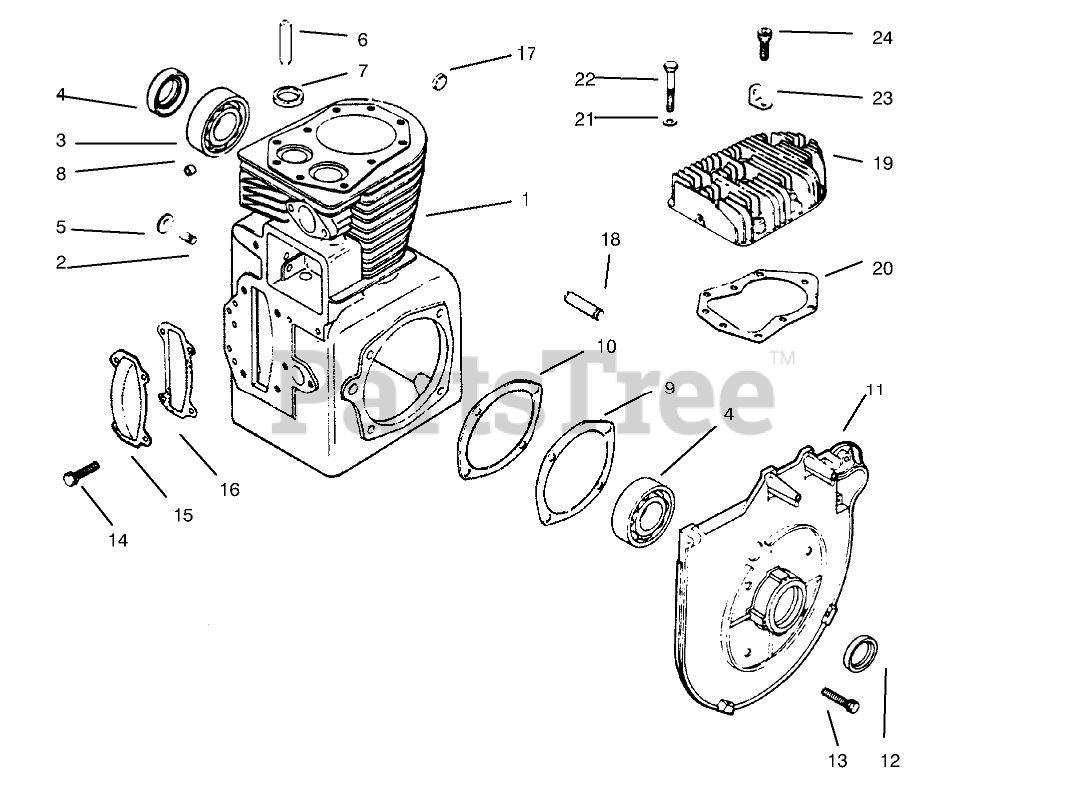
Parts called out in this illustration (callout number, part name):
1	Short Block 14hp
2	Shaft-Govemor
3	Ball Bearing
5	Plug
6	Guide Valve
7	Insert
8	Bearing
11	Plate-Bearing
13	Screw
14	Screw
15	Cover
16	Gasket
18	Shaft
19	Head-Cylinder
21	Washer
22	Screw
23	Strap-Lifting
